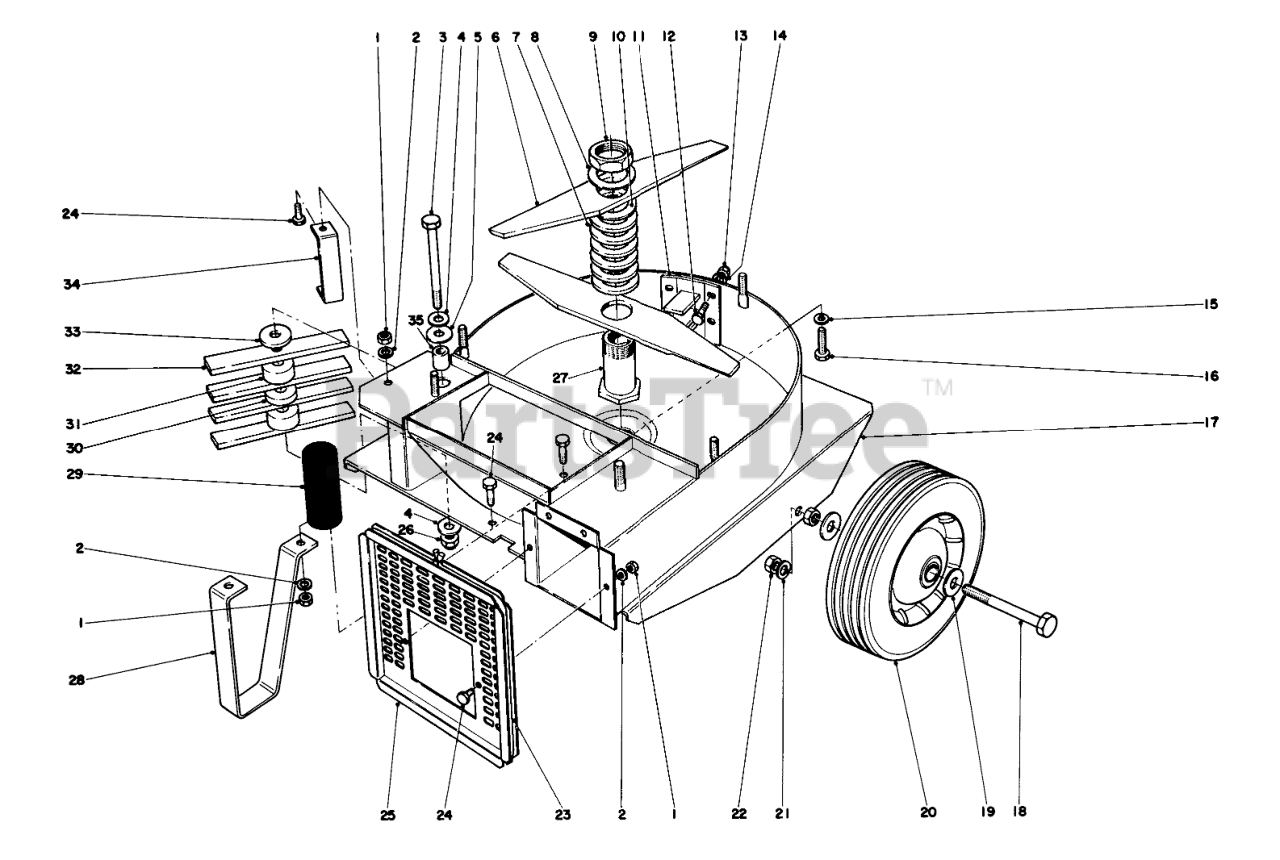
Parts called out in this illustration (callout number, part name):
1	NUT-HEX
2	WASHER-LOCK
3	Capscrew
4	Washer
5	Washer
6	Blade
7	Thick spacer
8	Washer
10	Spacer, rotor, thin
11	Secondary plate
12	SCREW-HH
13	NUT-HEX
14	WASHER-LOCK
15	WASHER-LOCK
16	SCREW-HH
18	SCREW-HH
19	WASHER-FLAT
20	Wheel & tire
21	WASHER-LOCK
22	NUT-HH
23	Bag cord
24	SCREW-HH
25	Bag plate
26	NUT-HEX
27	Rotor hub
28	Leg stand
29	Rubber shock
30	Spacer, finger thin
31	Spacer, thick
32	Finger shredder
33	Thin spacer
34	Finger backstop
35	Sleeve, finger
